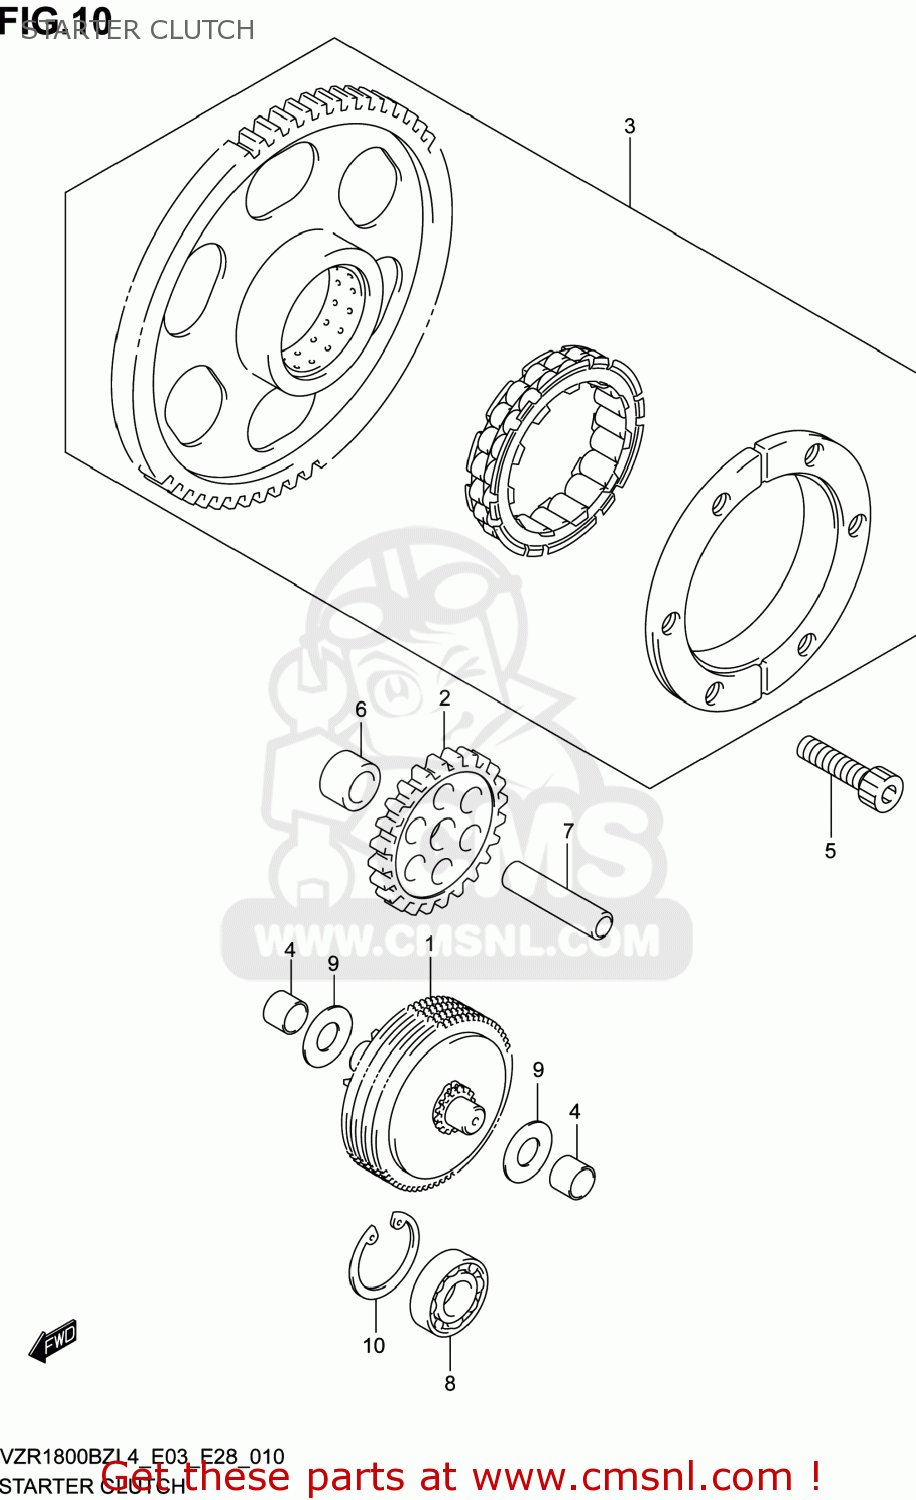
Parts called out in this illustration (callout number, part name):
1	LIMITER ASSY,START ID GR NO.1
2	GEAR,STARTER IDLE NO.2
3	CLUTCH SET,STARTER
4	BUSH,LIMITER GEAR SHAFT
5	BOLT(8X16)
6	SPACER(12.5X19X12.5)
7	PIN(8X12X45.5)
8	BEARING(12X28X8)
9	WASHER
10	CIRCLIP
